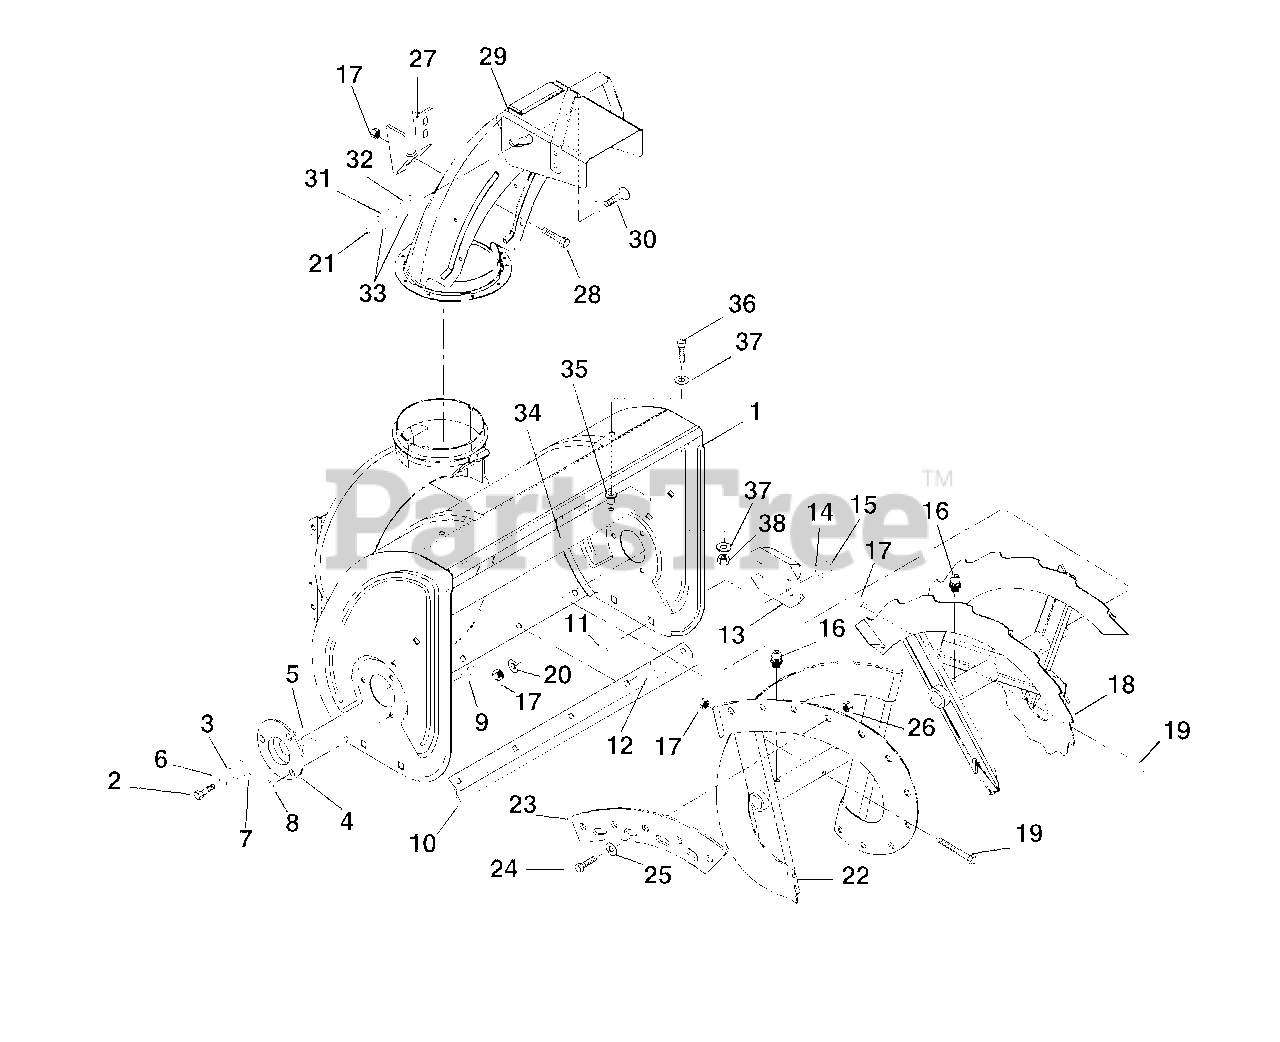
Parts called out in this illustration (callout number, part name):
1	HOUSING, BLOWER - 20"
1	HOUSING, BLOWER - 24"
1	HOUSING, 24" BLOWER
2	@BLT-HEX .31-18X.50 GR5 YWZC
3	WSHR-FL-STL .347X1.254X.048YWZ
4	BEARING FLANGE ASSEMBLY
5	@WSHR-FL-STL.812X1.50X.135YWZC
6	@WSHR-LK .31X.078 REG YWZC
7	BSHG-FLG .750X1.000X.625X1.250
8	@NUT-SPNLK-FLG .25-20 YWZC
9	BLT-SERNK SL .25-20X.50 YWZC
10	SCRAPER BLADE, 20"
10	SCRAPER BLADE
10	SCRAPER BLADE, 24"
11	BLT-RHHDSQSHNK .38-16X.75 G2YZ
12	BLT-RDHDSQSHNK.25-20X.50 YWZC
12	@BLT-RDHDSQNK .25-20X.50 G5YZ
13	SKID SHOE, REVERSIBLE - ORANGE
14	@WSHR-FL-STL.38X.875X.083 YWZC
15	@NUT-LK-CTR .38-16 YWZC
16	ZERK,FITTING .25X.125 DRIVE IN
17	@NUT-LK-CTR .25-20 YWZC
18	RAKE, RIGHT-24"(.75ID X 10.88)
18	RAKE, LEFT-24(.75ID X 10.88OD)
19	SHEAR BOLT WITH NUT
20	@WSHR-FL-STL.281X.62X.065 YWZC
21	@NUT-LK-CTR .31-18 YWZC
22	RAKE, RIGHT-20(.75ID X 10.5OD)
22	RAKE, RH 24" AUGER PROPEL
22	RAKE, LEFT-20"(.75ID X 10.5OD)
22	RAKE, LH 24" AUGER PROPEL
23	RAKE EDGE W/HARDWARE
23	RAKE EDGE W/HARDWARE - 24"
24	BLT-HEX 10-24X.63 PL
25	@WSHR-FL-STL .188X.438X.049 YZ
26	NUT-LK TOP 10-24 PL
27	CHUTE STRAP
28	@BLT-HEX .25-20X.50 GR5 YWZC
29	CHUTE, DISCHARGE W/CAP & DECAL
30	@BLT-RHDSSQNK .31-18X.75 G5YZ
31	WAVE WASHER .390X.655X.110
32	WSHR-PLASTIC .390X.875X.062
33	@WSHR-FL-STL.344X.688X.065YWZC
34	BAR, WEIGHT-5 LBS
35	BSHG, FLG .325X.499X.26X.88
36	@BLT-HEX .31-18X1.00 GR5 YWZC
37	@WSHR-FL-STL.344X.688X.065YWZC
38	@NUT-LK-CTR .31-18 YWZC
